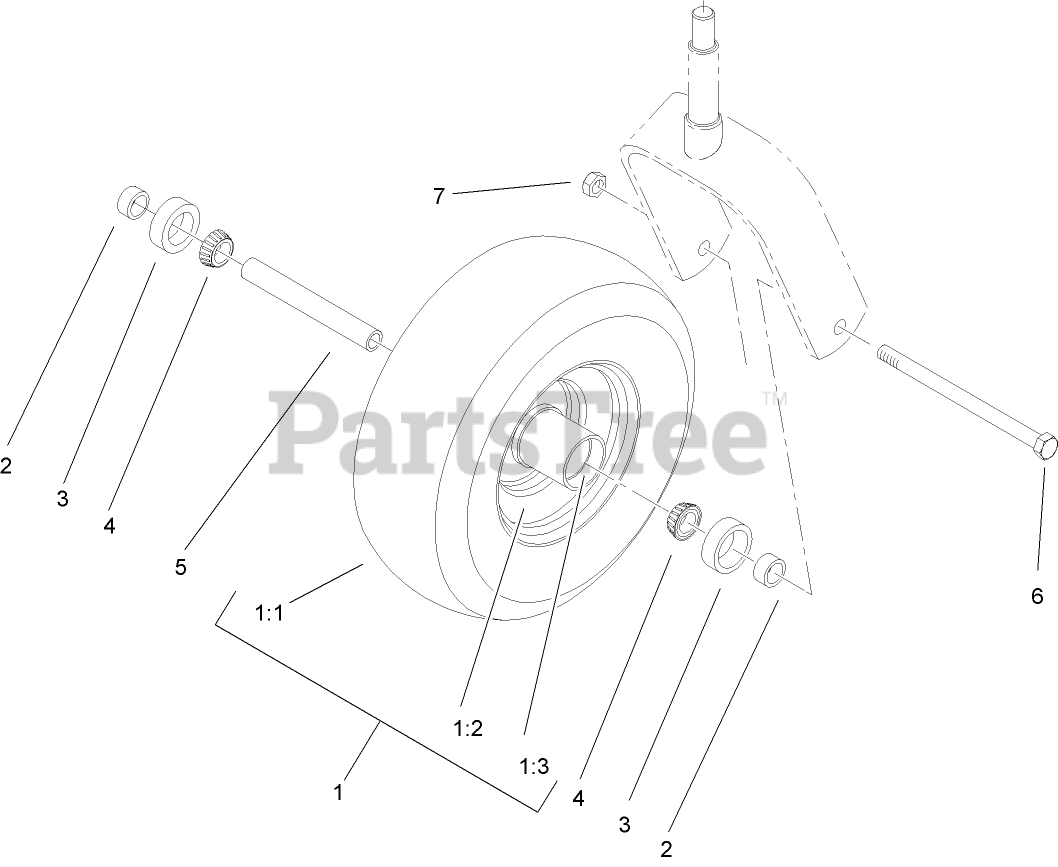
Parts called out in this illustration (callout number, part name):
1	WHEEL and TIRE ASM
1:3	BEARING-CUP
2	SPACER-BEARING
3	SEAL-BEARING
4	BEARING-CONE, TAPER
5	SPACER-CASTER, FRONT
6	SCREW-HH
7	NUT-LOCK, NI
